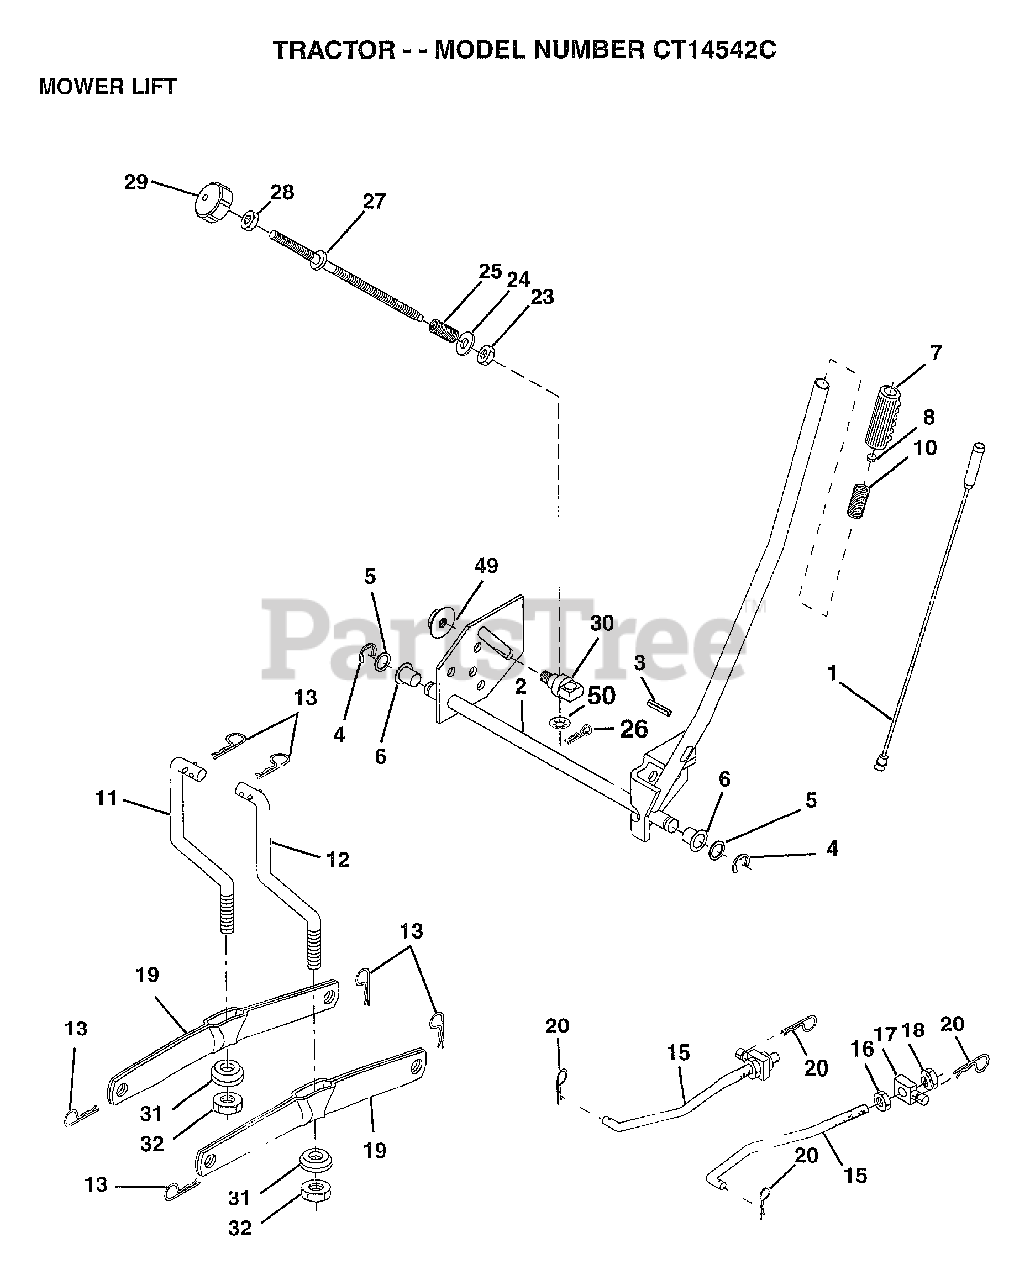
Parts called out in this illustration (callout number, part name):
1	WIRE.ASM.INNER
2	SHAFT.ASM.LIFT.RH
3	PIN GROOVE
5	WASHER
6	NYLON BEARING
7	GRIP
15	LINK.FRONT
16	NUT
17	TRUNION
18	NUT.LK.W/WSH.1/2.
19	ARM SUSP REAR
20	RETAINER.SPRING
23	NUT T
24	WASHER
25	SPRING.COMP.INF.H
27	ROD.ADJ.LIFT
28	NUT
29	KNOB INF 3/8-16
30	TRUNNION
31	BEARING PVT LH
32	NUT.CROWNLOCK.3/8
49	NUT.HXFLG.LOCK.
50	NUT PUSH M
